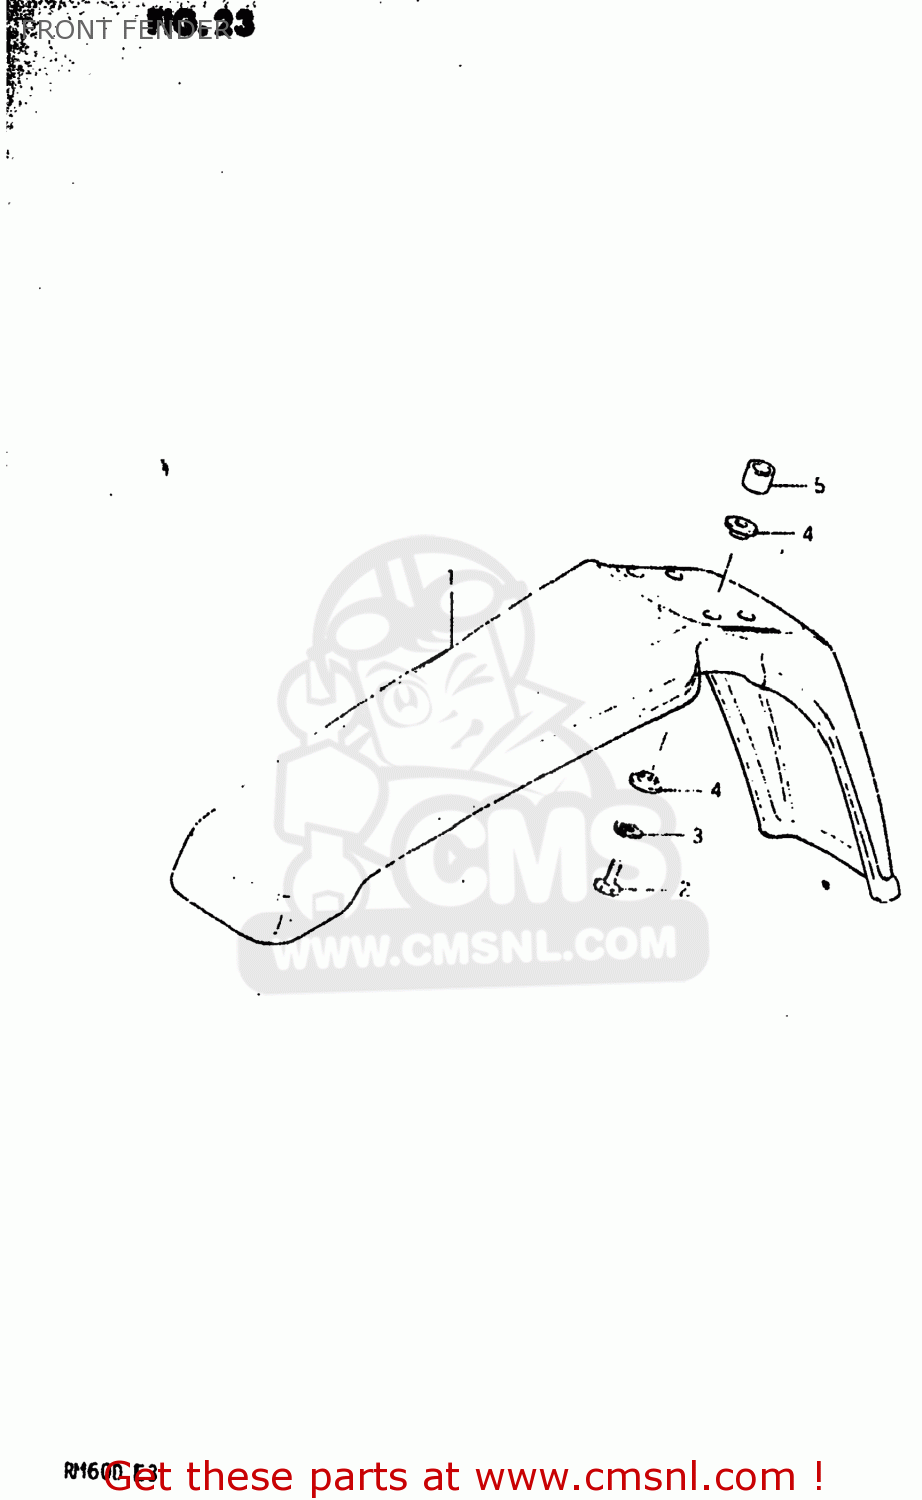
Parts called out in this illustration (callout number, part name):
1	FENDER,FRONT
2	BOLT
3	LOCK WASHER
4	SPACER
5	SPACER (6.8X10X10)
